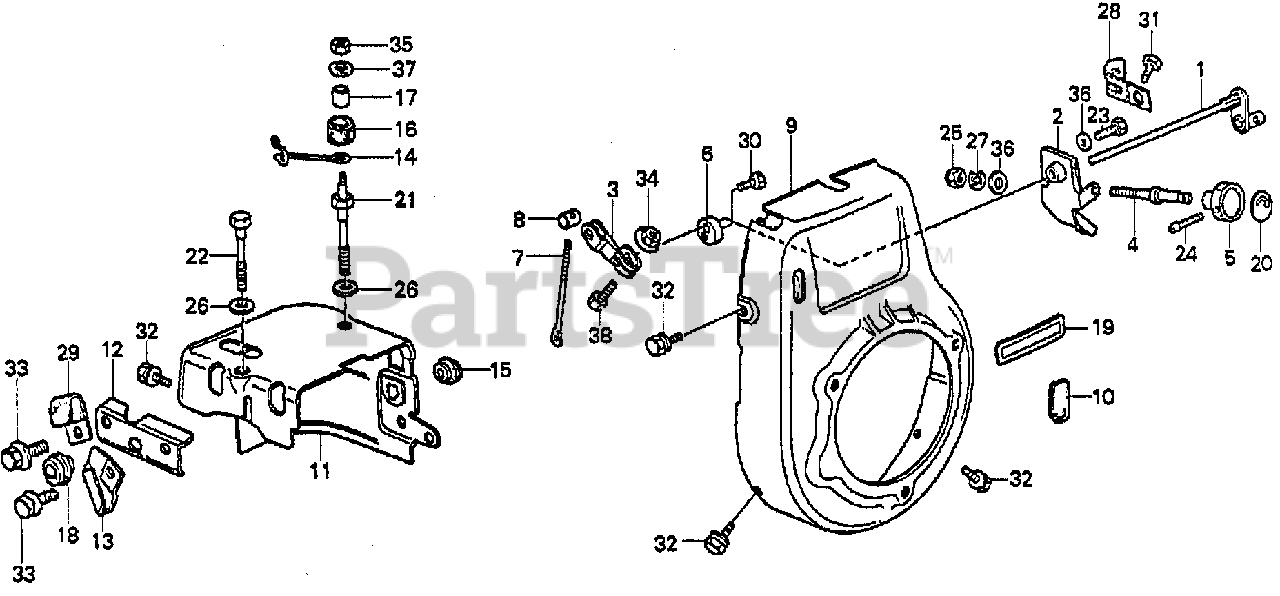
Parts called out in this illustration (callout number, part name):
1	SHAFT, CONTROL
2	BASE, CONTROL (NOT AVAILABLE)
3	ARM, CONTROL (NOT AVAILABLE)
4	SHAFT, ADJUSTING (NOT AVAILABLE)
5	KNOB, CONTROL
6	HOLDER, SHAFT
7	ROD, ADJUSTING
8	JOINT, ADJUSTING ROD (NOT AVAILABLE)
9	COVER, FAN *R8* (BRIGHT RED)
10	GROMMET, FAN COVER
11	COVER, SIDE *R8* (BRIGHT RED)
12	BRACKET, SIDE COVER
13	GUIDE, AIR
14	CLAMP, IGNITION WIRE (NOT AVAILABLE)
15	GROMMET, COVER (NOT AVAILABLE)
16	RUBBER, STOPPER (NOT AVAILABLE)
17	COLLAR, DISTANCE
18	GROMMET, CABLE
20	MARK, KNOB (NOT AVAILABLE)
21	BOLT, SPECIAL HEX.
22	BOLT, HEX. (10X76)
23	BOLT (6MM)
24	BOLT, KNOB (3MM) (NOT AVAILABLE)
26	WASHER, MAGNET FIXING
28	WIRE HARNESS (NOT AVAILABLE)
29	CLAMP, CORD (NOT AVAILABLE)
30	BOLT, HEX. (5X8)
31	BOLT, HEX. (6X8)
32	BOLT-WASHER (6X12)
33	BOLT-WASHER (8X20)
34	NUT, HEX. (6MM)
34	NUT, FLANGE (6MM)
35	NUT, HEX. (8MM)
36	WASHER, PLAIN (6MM)
37	WASHER, PLAIN (8MM)
38	BOLT, HEX. (6X20)
38	BOLT, FLANGE (6X20)
